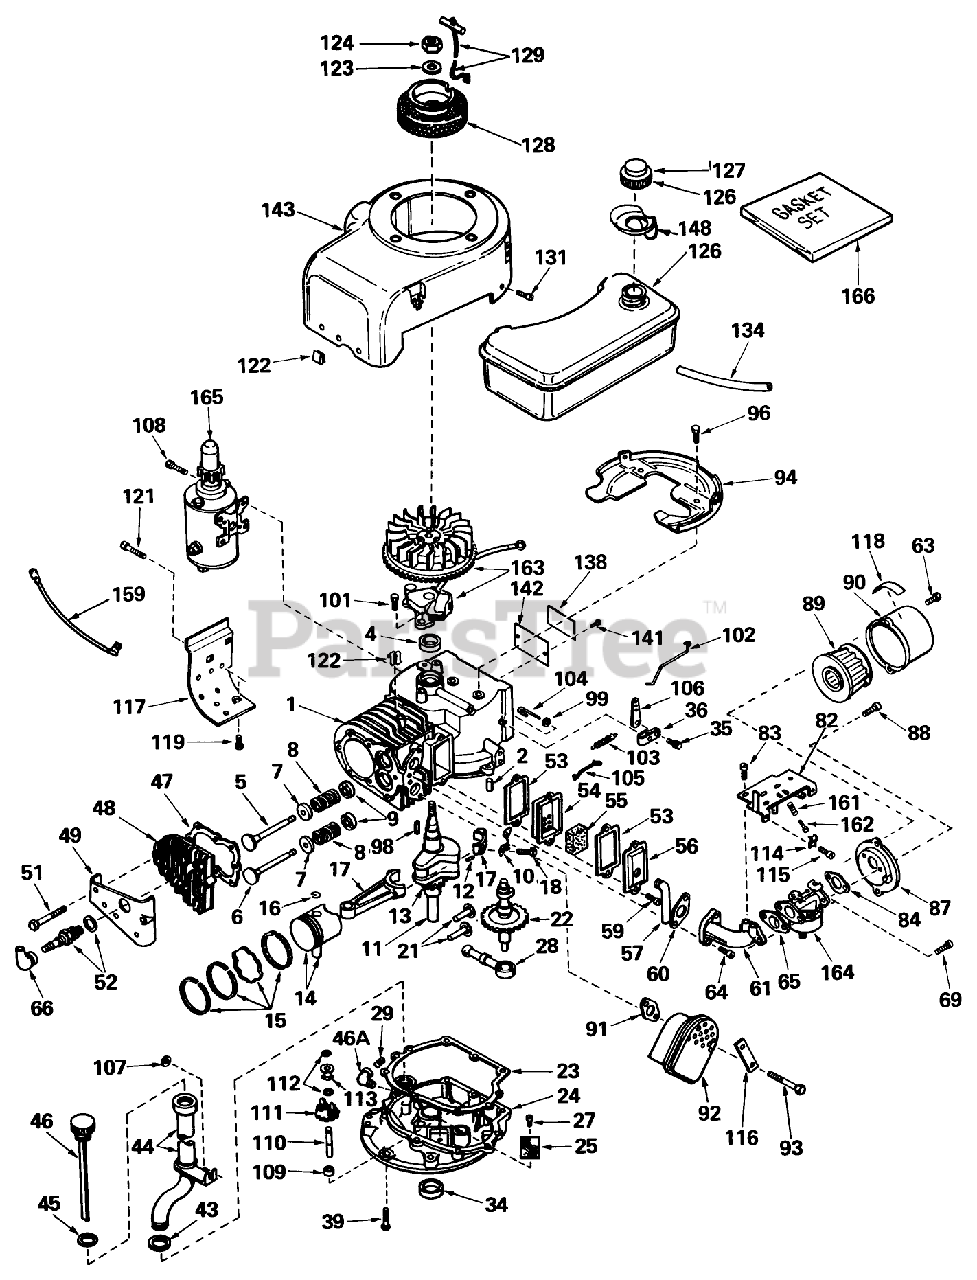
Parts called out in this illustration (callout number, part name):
1	Cylinder Assy. (Incl Nos. 2 4)
2	Pin-Dowel
4	Oil Seal
5	Valve, Intake (Standard)(Incl. No. 9)
5	Valve, Intake (1/32" oversize)(Incl. No. 9)
6	Valve, Exhaust (Standard)(Incl. No. 9)
6	Valve, Exhaust (1/32" oversize)(Incl. No. 9)
7	Cap-Spring, Valve
8	Spring-Valve
9	Keeper-Spring, Valve
10	Plate, Lock
11	Crankshaft Assy. (Incl. Nos. 12 13)(Model 935 only)
12	Pin, Groove
13	Gear-Crankshaft
14	Piston Pin Assy. (Incl. 2 of No. 16)(Standard)
14	Piston Pin Assy. (Incl. 2 of No. 16)(.010 oversize)
14	Piston Pin Assy. (Incl. 2 of No. 16)(.020 oversize)
15	ORing
15	Ring Set (.010" OS)
15	Ring Set (.020" OS)
17	Rod Assy., Connecting (Incl. Nos. 10 18)
18	Screw, Hex Hd.
21	Lifter Valve
22	Screw
23	Gasket-Cover, Cylinder
24	Flange Assy., Mounting (Incl. Nos. 25, 27, 29, 34 110)
25	Screen-Oil Filter
27	Screw
28	Pump, Oil
29	Plug-Drain, Oil (SQH 1/4-18)
34	Seal-Oil
35	Screw
36	Clamp-Lever, Governor
39	Screw (1/4-20 x 1-1/4)
43	O-Ring
44	Tube, Oil Fill
45	O-Ring
46	Plug Gauge Assy., Oil
46A	Elbow, 90
47	Gasket-Cylinder Head
48	CYLINDER HEAD
49	Cover-Head, Cylinder
51	Screw Hex Hd. Cap
52	Plug, Spark (J17LM or equiv.)
53	Gasket-Breather
54	Body-Breather
55	Element-Breather
56	Cover-Valve
57	Tube-Breather
59	Screw
60	Gasket-Intake
61	Pipe-Intake
63	Screw
64	Screw (T-30, 5/16-18x1-3/32)
65	Gasket
66	Cover-Spark Plug
69	Screw-Hex Hd.
82	Control Assy., Speed (Incl. Nos. 161 162)
83	Screw (10-24 x 9/16)
84	Gasket
87	Bracket
88	Screw (10-32 x 1/2)
89	Element
90	Body
91	Gasket Exhaust
92	Muffler
93	Screw Hex Hd.
94	Baffle Blower Housing
96	Screw (1/4-20x19/32)
98	Key-Flywheel
99	Washer-Flat
101	Screw
102	Link Governor
103	Spring Governor
104	Rod, Governor (Incl. Nos. 146)
105	Link Governor Spring
106	Lever-Governor
107	Washer
108	Screw
109	Spacer
110	Shaft, Governor
111	Governor Gear ASM
112	Ring-Retaining
113	Spool-Governor
114	Conduit
115	Screw (10-32 x 3/8)
116	62513 SNWTHWR W/284
117	Emnsion, Blower Housing
118	Decal
119	Screw
121	Screw
122	51004 GIL ROTARY TI
123	Washer
126	Tank Assy., Fuel (Incl. No. 127)
127	Cap, Fuel
128	Hub Screen, Rope Starter
129	Rope Assy., Starter
131	Screw, Hex Hd.
134	Line-Fuel (8.62)
138	480B GIL SNWTHWR O/
141	Stud
142	IDENTIFICATION PLATE
143	Housing Blower
148	Deflector-Fuel
159	SPOOL RETAINER (10-PK)
161	Spring-Compression
162	Screw
163	Magneto
164	Carburetor
165	Motor, Starter
165	Tine Shaft
166	Gasket Set
